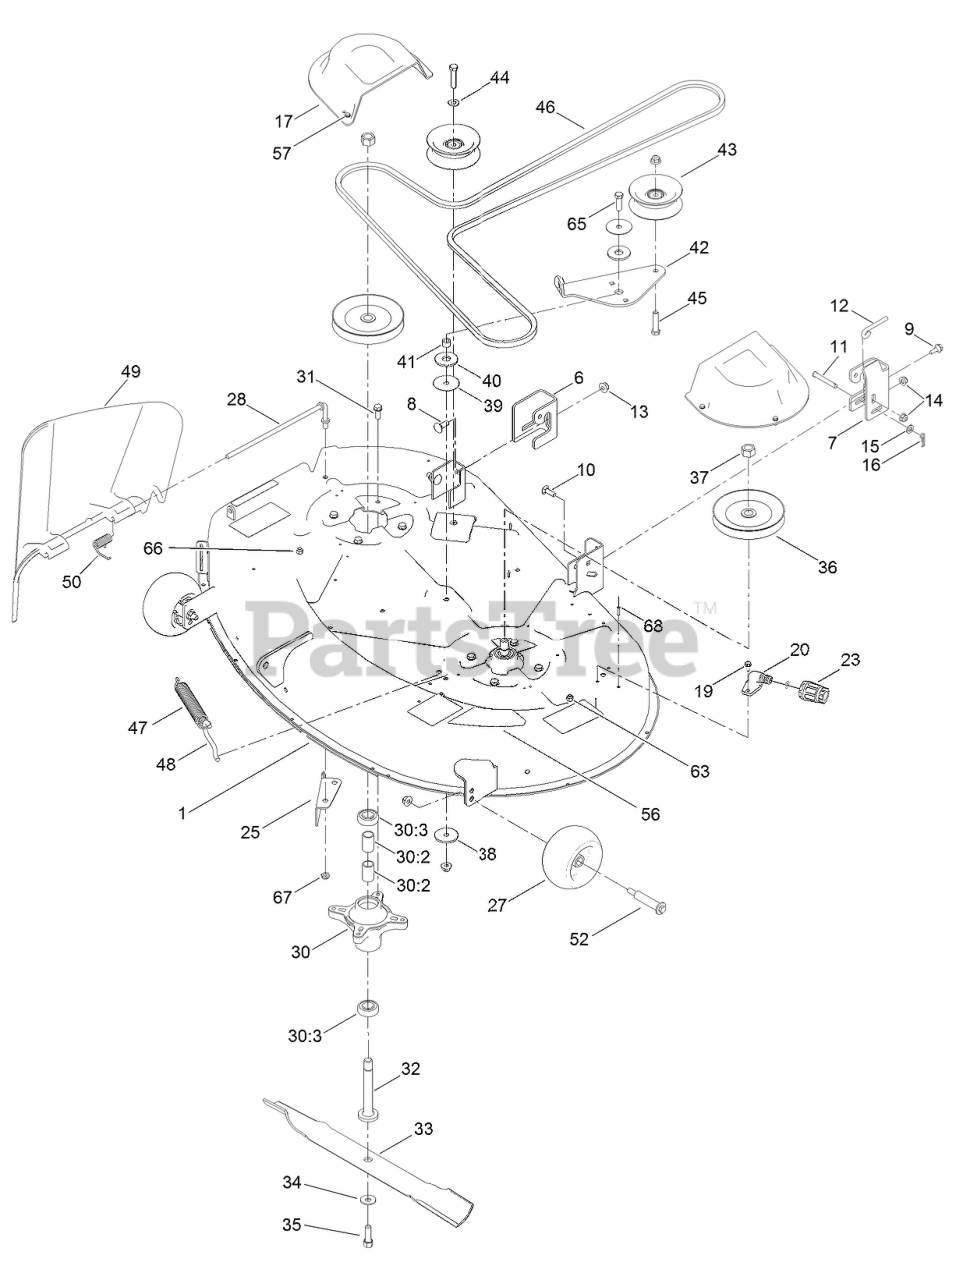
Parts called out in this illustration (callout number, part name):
1	42 INCH DECK AND DECAL ASM
6	BRACKET-HANGER, RH
7	BRACKET-HANGER, LH
8	BOLT-CARR
9	SCREW-SHOULDER, HHF
10	SCREW-CARR
11	PIN-CLEVIS
12	ROD-LEVEL, DECK
13	NUT-HF, NI
14	NUT-HF, NI
15	WASHER-PLAIN
16	PIN-COTTER
17	COVER-BELT
19	SCREW-HWH
20	FITTING-WASHOUT
23	CONNECTOR-HOSE
25	BAFFLE-CUTOFF
27	ROLLER-SCALP, ANTI
28	ROD-PIVOT
30	SPINDLE ASM
30:2	SPACER
30:3	BEARING-BALL
31	SCREW-TAPTITE
32	SHAFT-SPINDLE
33	BLADE-HIGH LIFT
34	WASHER-BELLEVILLE
35	SCREW-HH
36	Pulley
37	NUT-HEX
38	WASHER-REBOUND
39	WASHER
40	WASHER-FRICTION, COMPOSITE
41	SPACER
42	ARM-IDLER
43	PULLEY-IDLER, FLAT
44	WASHER-FLAT
45	SCREW-HH
46	V-BELT
47	SPRING-EXTENSION
48	HOOK-RETURN, SPRING
49	DEFLECTOR
50	SPRING-TORSION
52	BOLT-SHOULDER
57	SCREW-TAPTITE
63	NUT-LOCK, NI
65	SCREW-HH
66	SCREW-HH
67	NUT-LOCK, NI
68	RIVET-BLIND
